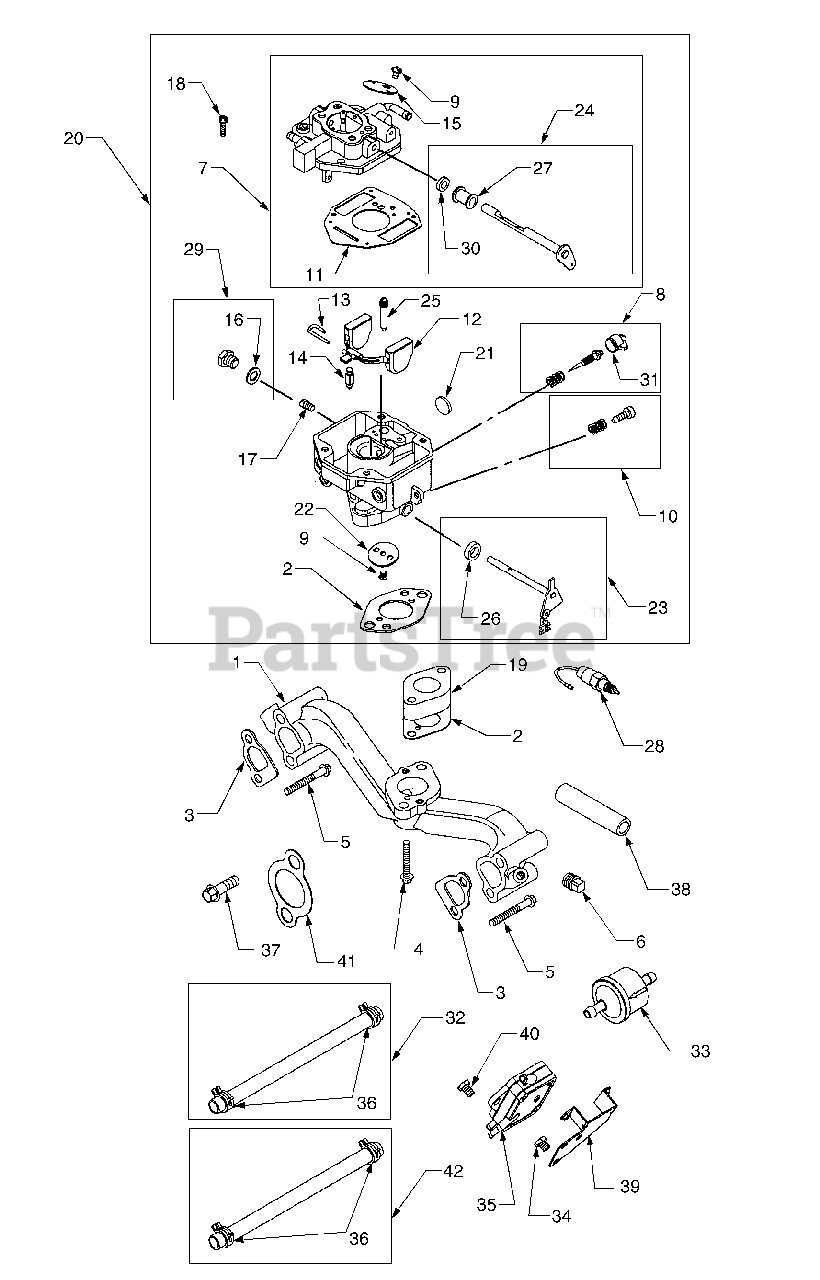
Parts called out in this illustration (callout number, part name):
1	Manifold, Intake
2	Gasket, Intake
3	Gasket, Intake
4	Screw, Hex
5	Screw, Hex
6	Plug, Oil
7	Body Assembly, Upper
8	Valve, Idle Adjust
9	Screw, Slotted
10	Screw, Throttle Adjust
11	Gasket, Carburetor Body
12	Float, Carburetor
13	Pin, Float Hinge
14	Valve, Fuel Inlet
15	Valve, Choke
16	Washer, Seal
18	Screw, Hex
19	Spacer, Carburetor
20	Carburetor Assembly
21	Plug, Welch
22	Valve, Throttle
23	Shaft and Lever, Throttle
24	Shaft, Choke
25	Nozzle, Carburetor
26	Collar, Throttle
27	Collar, Choke
28	Solenoid, Fuel
29	Plug, Carburetor
30	Seal, Shaft
31	Cap, Limiter
32	Line, Fuel
33	Filter, Fuel
34	Screw, Hex
35	Pump, Fuel
36	Clamp, Fuel Line
37	Screw, Hex (Exhaust Manifold Mtg)
38	Insulation, Fuel Line
39	Bracket, Fuel Pump
40	Screw, Hex
41	Gasket, Exhaust
42	Line, Vacuum
